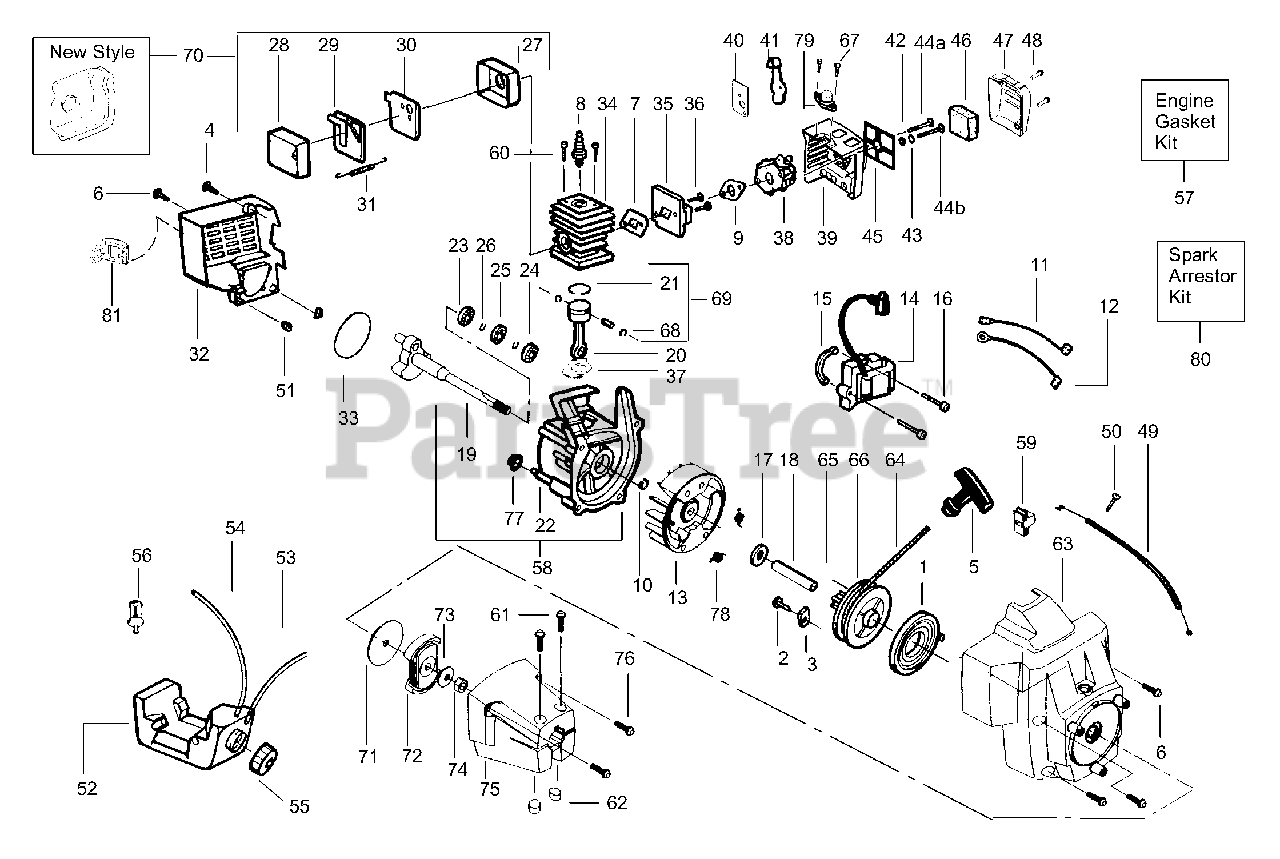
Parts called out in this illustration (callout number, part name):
1	Starter Spring
3	Retainer
5	Starter Handle
6	Screw
7	Gasket-Cyl/Carb Adapt
8	Spark Plug
9	Gasket-Carb
10	Retainer Ring (C'shaft)
11	Lead Wire Ass'y.
12	Ground Wire Ass'y.
13	Flywheel Ass'y.
14	Ignition Module
14	Service Ref. (C)
14	Service Ref. (D)
15	Spacer-Ign. Module
18	Spacer-Flywheel
19	Crankshaft Ass'y.
20	Connecting Rod Ass'y.
21	Piston Ring
21	Service Ref. (C)
21	Service Ref. (D)
22	Crankcase Ass'y.
23	Inner Bearing
24	Outer Bearing
25	C'case Seal
26	Retaining Ring (C'case)
27	Muffler Body
28	Muffler Cover
29	Muffler Baffle-Exit
30	Muffler Baffle-First
31	Muffler Spring
31	Old Style
31	New Style
32	Shroud
32	Service Ref. (C)
32	Service Ref. (D)
33	O-Ring-C'case/Shroud
34	Cylinder Kit
34	Service Ref. (C)
34	Service Ref. (D)
35	Carb. Adaptor Kit
36	Screw
36	Service Ref. (C)
36	Service Ref. (D)
37	Gasket-Cylinder
38	Carburetor Ass'y.
38	(WT380) Ser. Ref. (C)
38	(WT380) Ser. Ref. (D)
39	Air Box
39	Service Ref. (C)
39	Service Ref. (D)
40	Choke Mounting Plate
41	Choke Shutter
43	Spacer-Choke
44A	Screw-Carb Screw
44B	Screw-Carb. Screw
45	Support Plate/Filter
46	Air Filter Foam
47	Cover-Air Box
49	Throttle Cable Ass'y.
51	Isolator-Shroud
52	Fuel Tank Ass'y.
53	Fuel Line-Tank/Purge
54	Fuel Line-Carb/Purge
55	Fuel Cap Ass'y.
56	Fuel Pickup Ass'y.
57	Engine Gasket Kit
58	C'case & C'shaft Assy.
59	Switch Kit
63	Fan Housing Kit
63	Service Ref. (C)
63	Service Ref. (D)
64	Rope Kit
66	Starter Pulley
68	Piston Pin Retainer
69	Piston Kit
69	Service Ref. (C)
69	Service Ref. (D)
70	Muffler Kit
70	Old Style
70	New Style
71	Washer-Clutch
72	Clutch Ass'y.
73	Washer-Flat
75	Clutch Hsg.
75	Service Ref. (C)
75	Service Ref. (D)
77	Isolator-Crankcase
78	Spring-Starter Dog
79	Bulb Ass'y.
80	Spark Arrestor Kit
80	Old Style
80	New Style
81	Guard-Muffler
